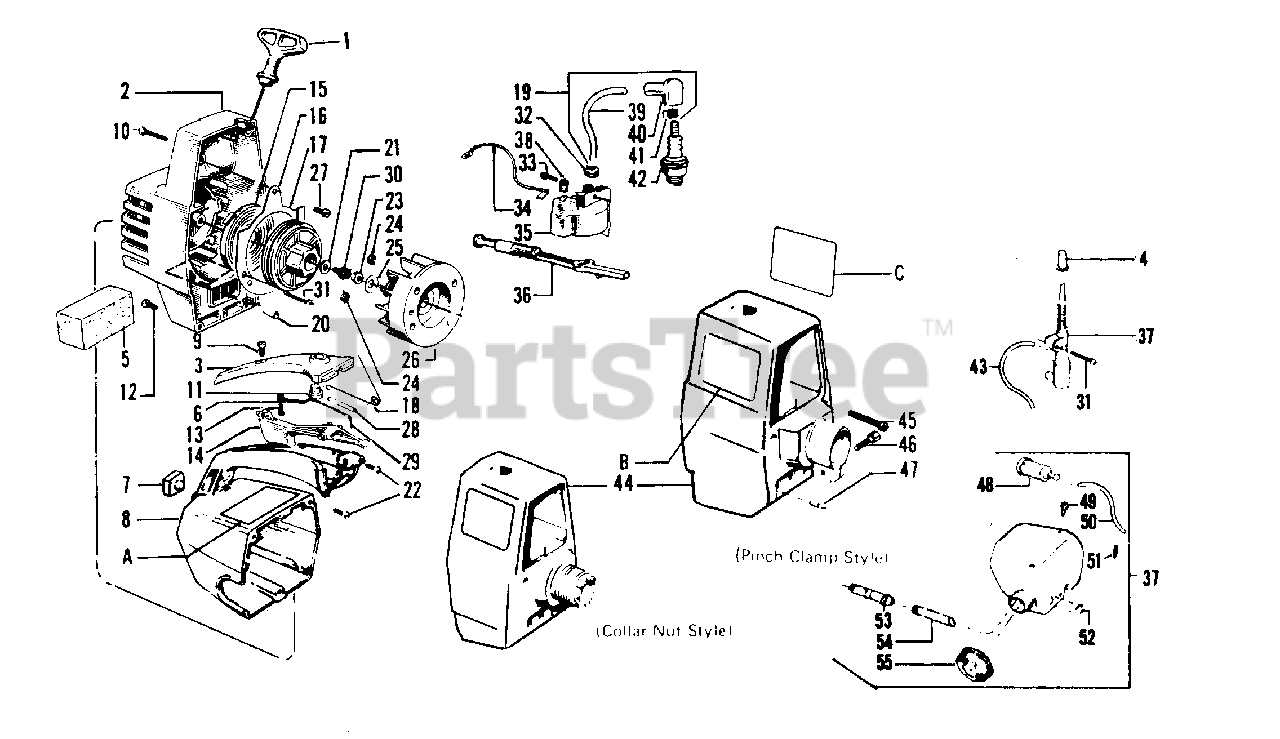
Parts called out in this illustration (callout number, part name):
1	Starter Handle
2	Fan Housing Kit - (Inc.16,20,27,28,31) See Service Reference 5
3	Handle Cover
4	Injector Button - Type 2 only
5	Air Filter
6	Washer - Kill Switch
7	Bumper - Fuel Tank Housing
8	Handle & Fuel Tank Housing
9	Screw - #8 - 16 x 3/4" - Pan Hd. - Handle Cover
11	Button - Kill Switch
13	Screw - #8 - 16 x 3/8" - Pan Hd. - Kill Switch
14	Trigger - Throttle
16	Air Baffle
18	Trigger Spring
19	BEVEL GEAR COMPLETE
20	Spacer - Type 1 only
21	Washer - #10 Starter Pulley
22	Screw - #10 - 14 x 3/4" - Pan Hd. - Fan Hsg. to Handle & Fuel Tank
23	Nut - Flywheel - #5/16 x 24 - Fil. Head
24	Spring - Starter Dog
25	Washer - Flywheel
26	Flywheel Ass'y. (Inc.24)
28	Insulation - Switch
29	Spring - Kill Switch
32	Grommet - Plug Wire
33	Screw - #8 - 32 x 3/4" - Fil. Hd. - Ignition Module
34	Lead Wire - Switch
35	Kit - Ignition Module
36	Knob - Choke - Type 1 only
37	Pump Ass'y. - Type 2 only
38	Electrical Tab 45 degree
39	High Tension Lead Wire
40	Boot - Spark Plug
41	Connector - Spark Plug Lead
42	Spark Plug
43	Pump to Accumulator Line - Type 2 only
44	Shroud, Pinch Clamp Style
44	Shroud, Screw Collar Style
45	Screw - #10 - 24 x 1-1/3" - Fil. Hd. - Shroud (Top)
46	Bolt - #1/4 - 20 x 1" Pinch Clamp
47	Screw - #10 - 24 x 5/8" - Fil. Head - Shroud (Bottom)
48	Fuel Pick-Up Ass'y. Type 1
48	Fuel Pick-Up Ass'y. Type 2
49	Duck Bill Check Valve
50	Fuel Line, Type 1
50	Fuel Line, Type 2
51	Fuel Line Fitting - Type 1 only
52	Clip - Retainer - Inlet Line - Fuel Tank Type 2 only
53	Fuel Filter (Inlet Line) - Type 2 only
54	Fuel Inlet Line - Type 2 only
55	Fuel Cap Ass'y. (Incl. "O" Ring)
56	Rope Kit
A	Starting Instructions - Decal, Type 1
A	Starting Instructions - Decal, Type 2
B	Decal - Shroud (Right)
C	Decal - Shroud (Left)
